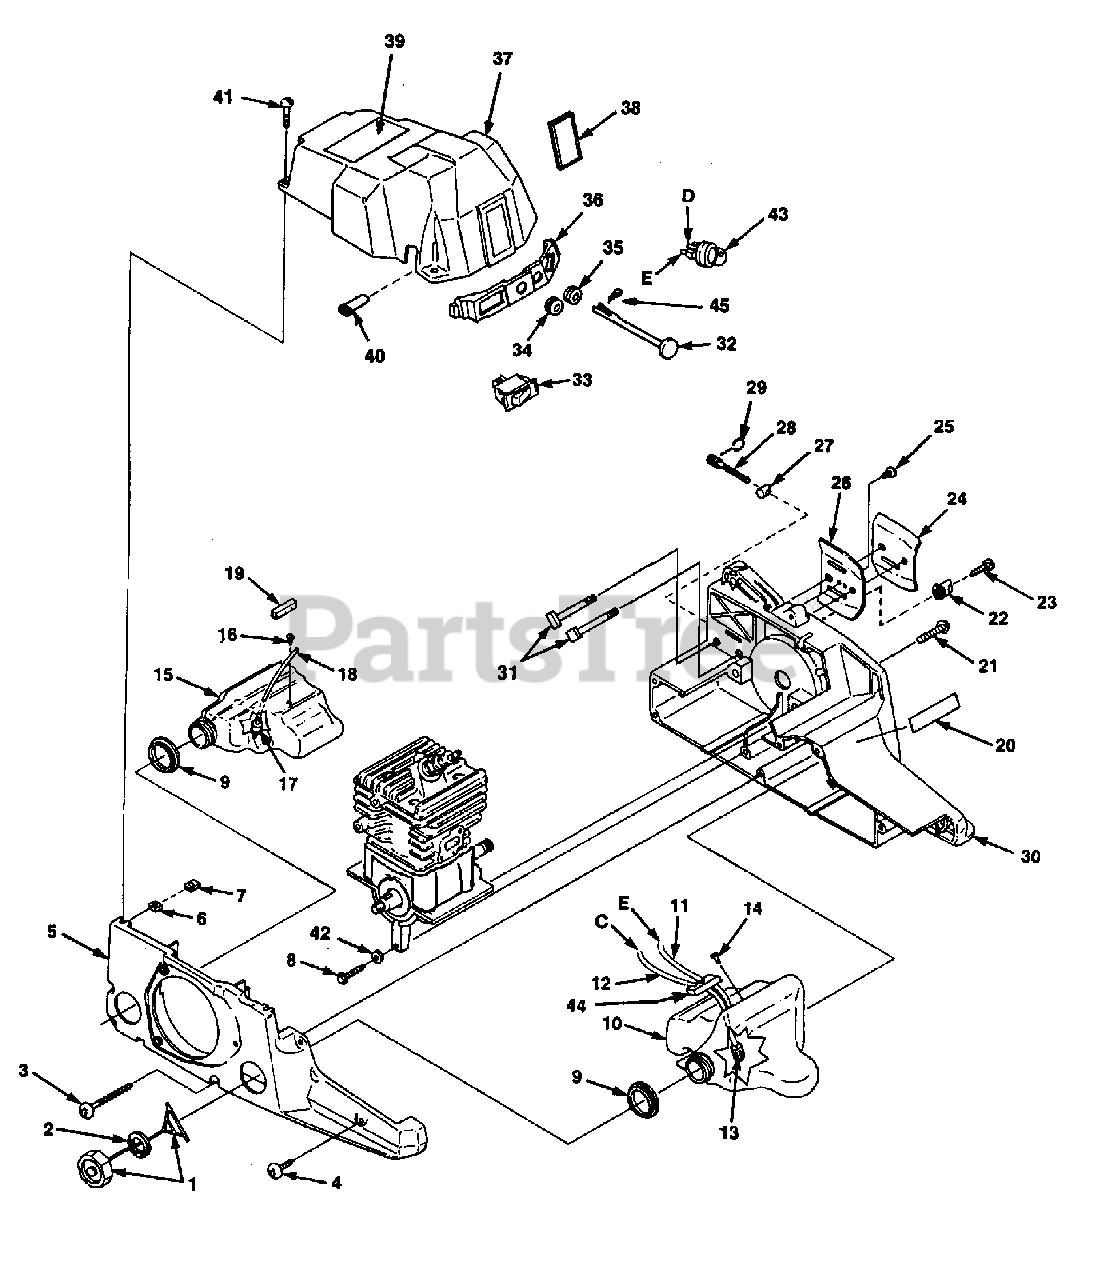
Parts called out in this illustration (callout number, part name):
1	CAP- Tank (w/retainer)
2	GASKET
3	SCREW (8-16 x 1 3/4")
4	SCREW- (8-16 x 5/8")
5	HOUSING- Starter side
6	NUT- Square (10-24)
7	NUT- Retainer
8	SCREW- Thd. forming (10-14 x 1 1/8")
9	SEAL- Tank
10	TANK- Fuel
11	TUBING- Rubber
12	TUBING- Rubber
13	FILTER- Fuel
14	VALVE- Check
15	TANK- Oil
16	VALVE- Check
17	FILTER- Oil
18	TUBING- Rubber
19	FILTER- Foam
20	DECAL- Panel
21	SCREW (12-24 x 1")
22	STOP- Chain
23	SCREW (10-14 x 7/8")
24	PLATE- Guide bar (outer)
25	SCREW (6-19 x 1/2")
26	PLATE- Guide bar (inner)
27	PIN-Adjusting
28	SCREW- Adjusting
29	RING- Snap
30	HOUSING- Drive side
31	BOLT- Guide Bar
32	ROD- Choke
33	SWITCH
34	BOOT- Throttle cable
35	GROMMET- Choke
36	PANEL- Control
37	COVER- Cylinder Assy.
38	SCREEN- Air inlet
39	DECAL- Warning
40	GROMMET- Carburetor
41	SCREW- (10-24 x .710)
42	WASHER- Lock
43	BULB- Primer
44	FILTER- Foam
45	PIN- Cotter
